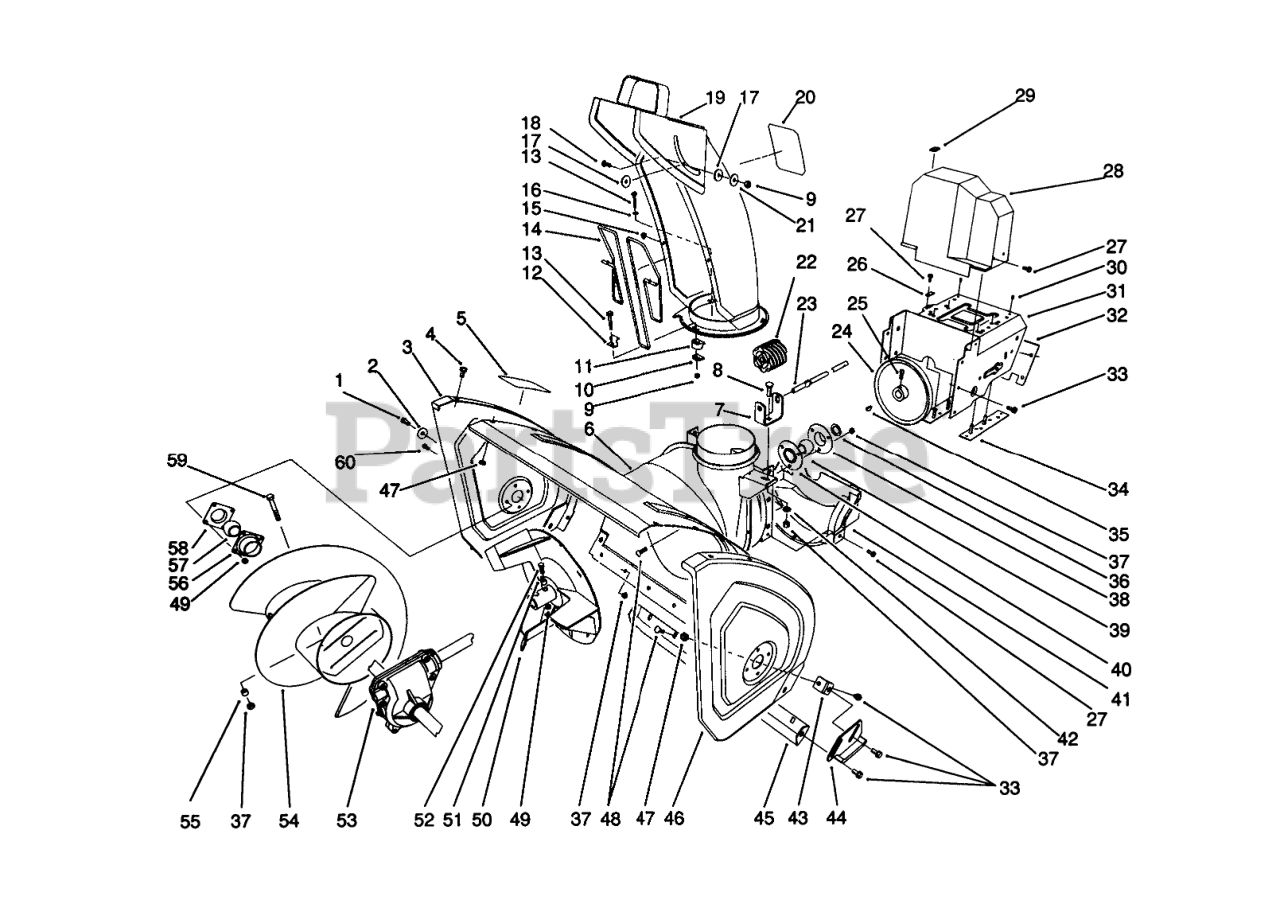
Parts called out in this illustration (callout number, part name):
1	SCREW-HH
2	WASHER
3	PLATE-SIDE, RH
4	SCREW-HHF
5	DECAL-WARNING, AUGER
6	Housing-24 Inch
7	BRACKET-WORM, CHUTE
8	BOLT-CARR
9	NUT-LOCK, NI
10	PLATE-RETAINER, CHUTE
11	RETAINER-CHUTE
12	CLIP-GUARD, CHUTE
13	SCREW-HSH
14	GUARD-CHUTE
15	NUT-PUSH
16	WASHER-FLAT
17	WASHER-PLASTIC
19	Assembly
20	DECAL-DANGER DISCH.
21	WASHER-FLAT
22	GEAR-WORM
23	ROD-CHUTE, LOWER
24	PULLEY-IMPELLER
25	SCREW-SET, SQH
26	RETAINER-CABLE
27	SCREW-HWH
28	COVER-BELT, UPPER
29	COVER-CABLE
30	RIVET-POP
31	Frame-Engine
32	Cover-Frame, Engine
33	SCREW-HHF
34	LH FRAME PLATE ASM
35	KEY-WOODRUFF
36	WASHER-THRUST
37	NUT-LOCK, NI
38	Flange-Bearing (Front)
39	BEARING-BALL
40	Flange-Bearing (Rear)
41	Cover-Belt (Lower)
42	WASHER-PLAIN
43	Bracket-Skid
44	SKID WA
45	Blade-Scraper
46	Plate-Side LH
47	NUT-LOCK, NI
48	SCREW-CARR
49	NUT-LOCK, NI
50	Impeller
51	SPACER
52	SCREW-HHF
53	Auger Gearbox ASM
54	Auger-RH
55	SPACER-HUB, AUGER
56	BEARING-FLANGE, FRONT
57	BEARING
58	BEARING-FLANGE, REAR
59	Auger Bolt
60	SCREW-HH
